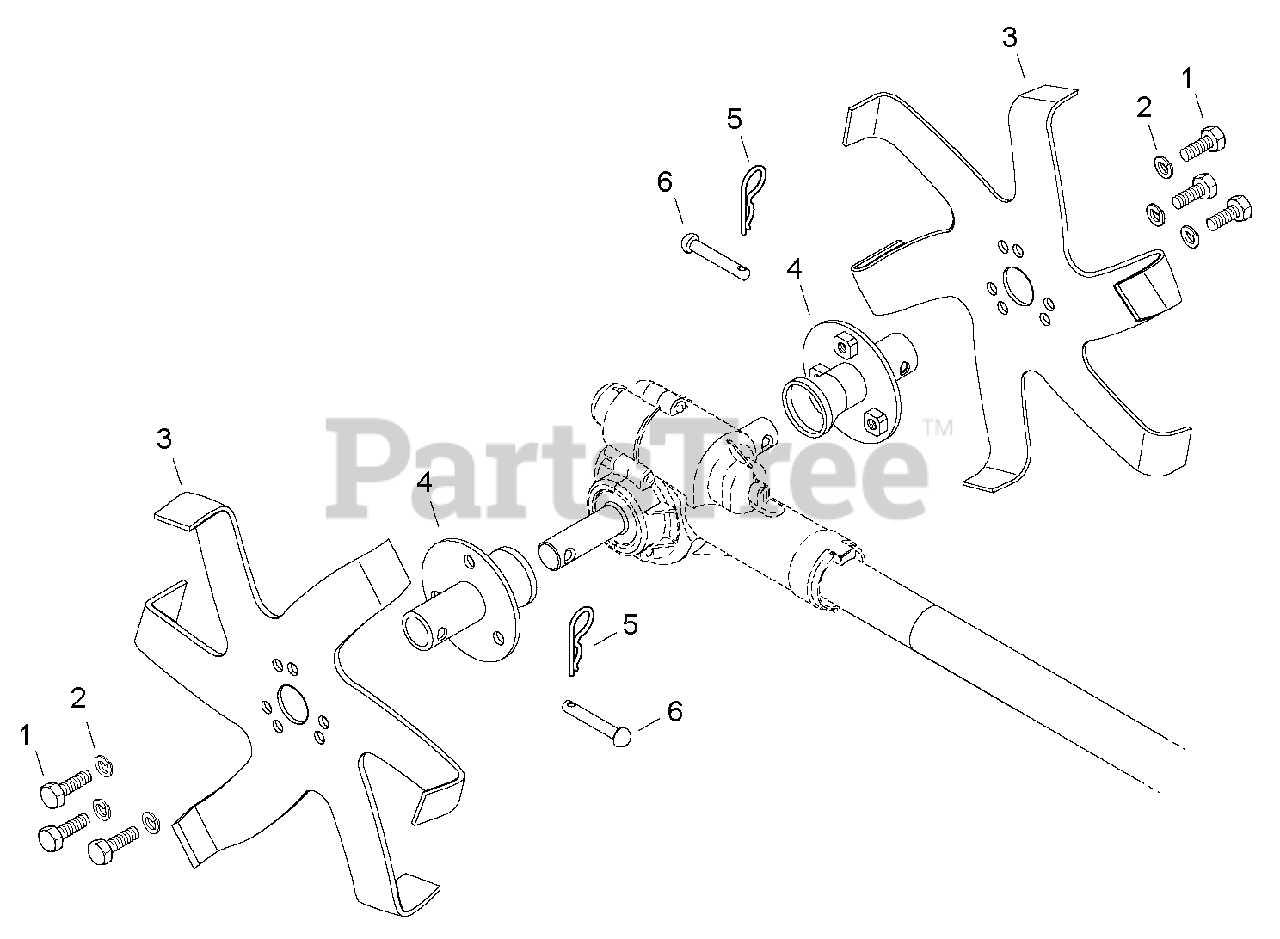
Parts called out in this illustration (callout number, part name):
1	BOLT - 6X10
2	LOCKWASHER - 6
3	BLADE, CULTIVATOR
4	HUB, CLUTCH
5	PIN, SPLIT
6	PIN, CLEVIS
